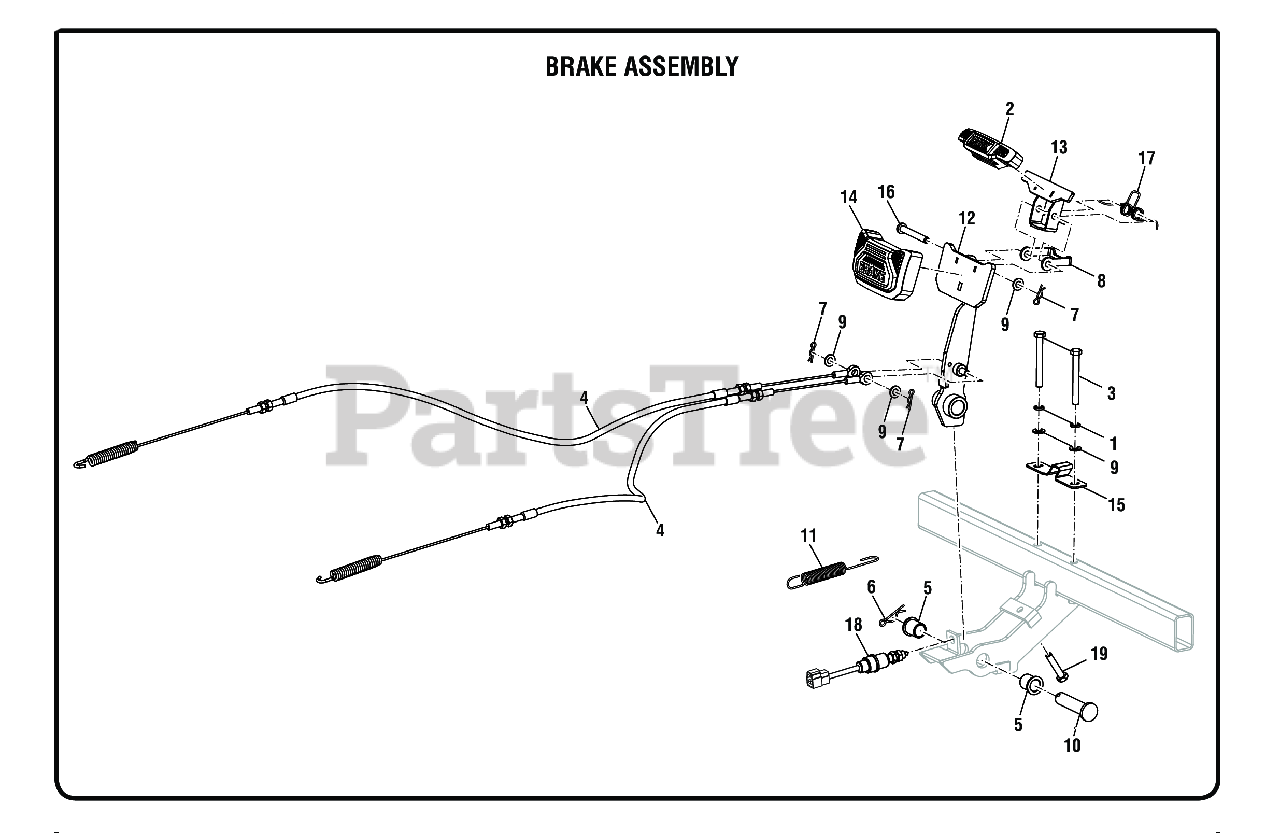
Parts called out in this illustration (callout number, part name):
1	Lock Washer (OD9.8 x ID8.5 x 5t)
2	Parking Brake Rubber Pad
3	Bolt (M8 x 70 mm, Hex Hd.)
4	Brake Cable
6	Lock Pin (16 mm)
7	Cotter Pin (8 mm)
8	Parking Brake Latch
9	Washer (OD16 x ID8.4 x 1.6t)
10	Clevis Pin
11	Brake Pedal Spring
12	Brake Pedal Lever
13	Parking Brake Pedal
14	Brake Pedal Rubber Pad
15	Brake Latch Hook
16	Clevis Pin (M8 x 60 mm)
17	Parking Brake Torsion Spring
18	Brake Switch Assembly
19	Bolt (M8 x 40 mm, Hex Hd.)
